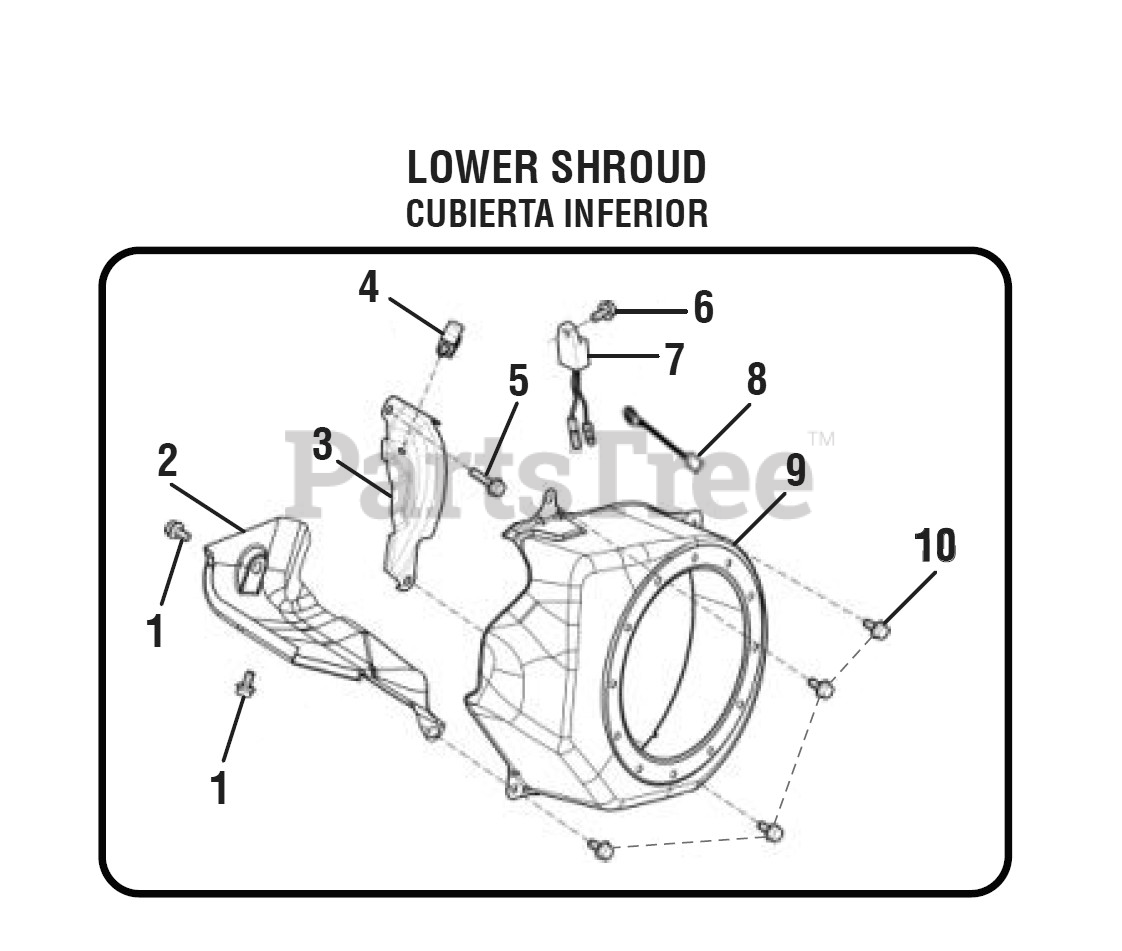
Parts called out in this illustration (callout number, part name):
2	Cylinder Body Shroud
3	Lower Shield
4	Collar
7	Oil Protector
8	Engine Stop Wire
